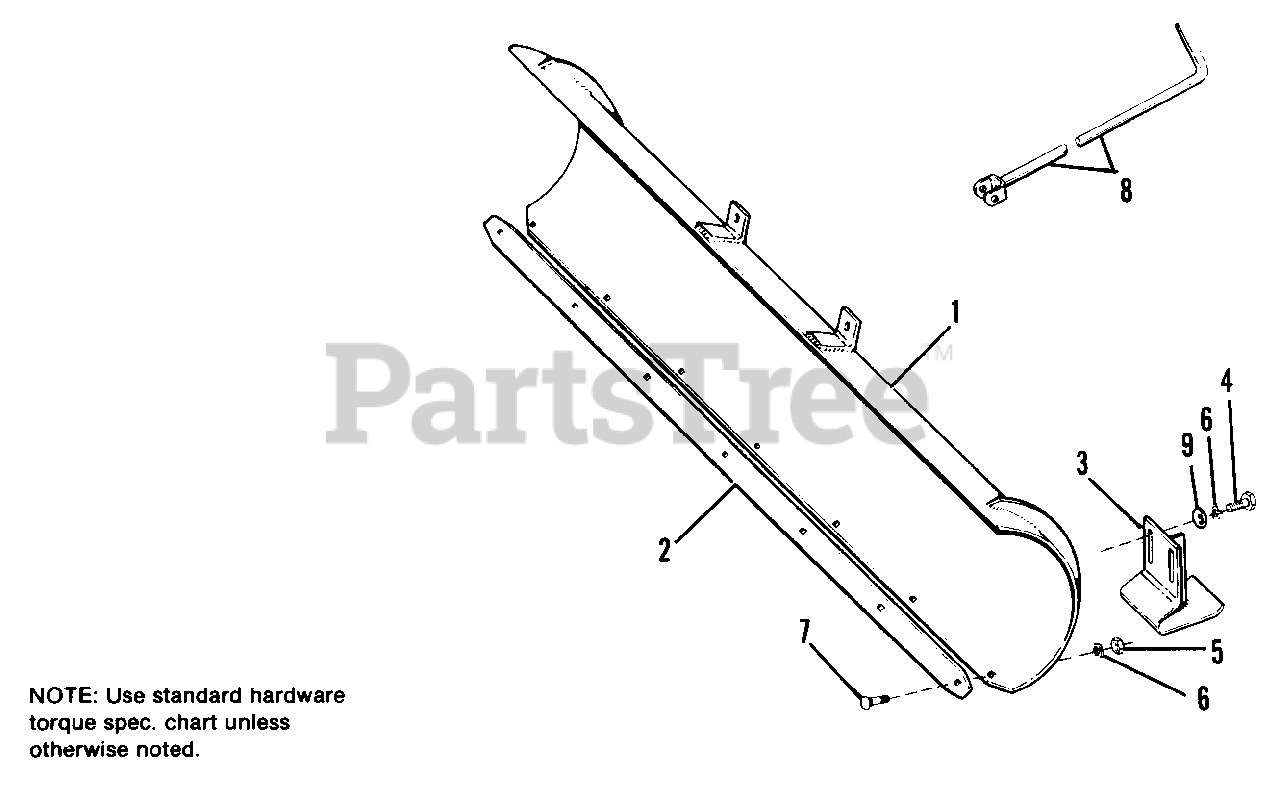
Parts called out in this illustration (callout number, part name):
1	BLADE ASSY.
2	PLATE, Wear
3	SHOE ASSY.
4	CAPSCREW, Hex Hd., 3/8-16 x 3/4
5	NUT, Hex, Full, 3/8-16
6	LOCKWASHER, 3/8
7	CARRIAGE BOLT, 3/8-16 x 1
8	ROD ASSY., Control
9	WASHER, Flat
